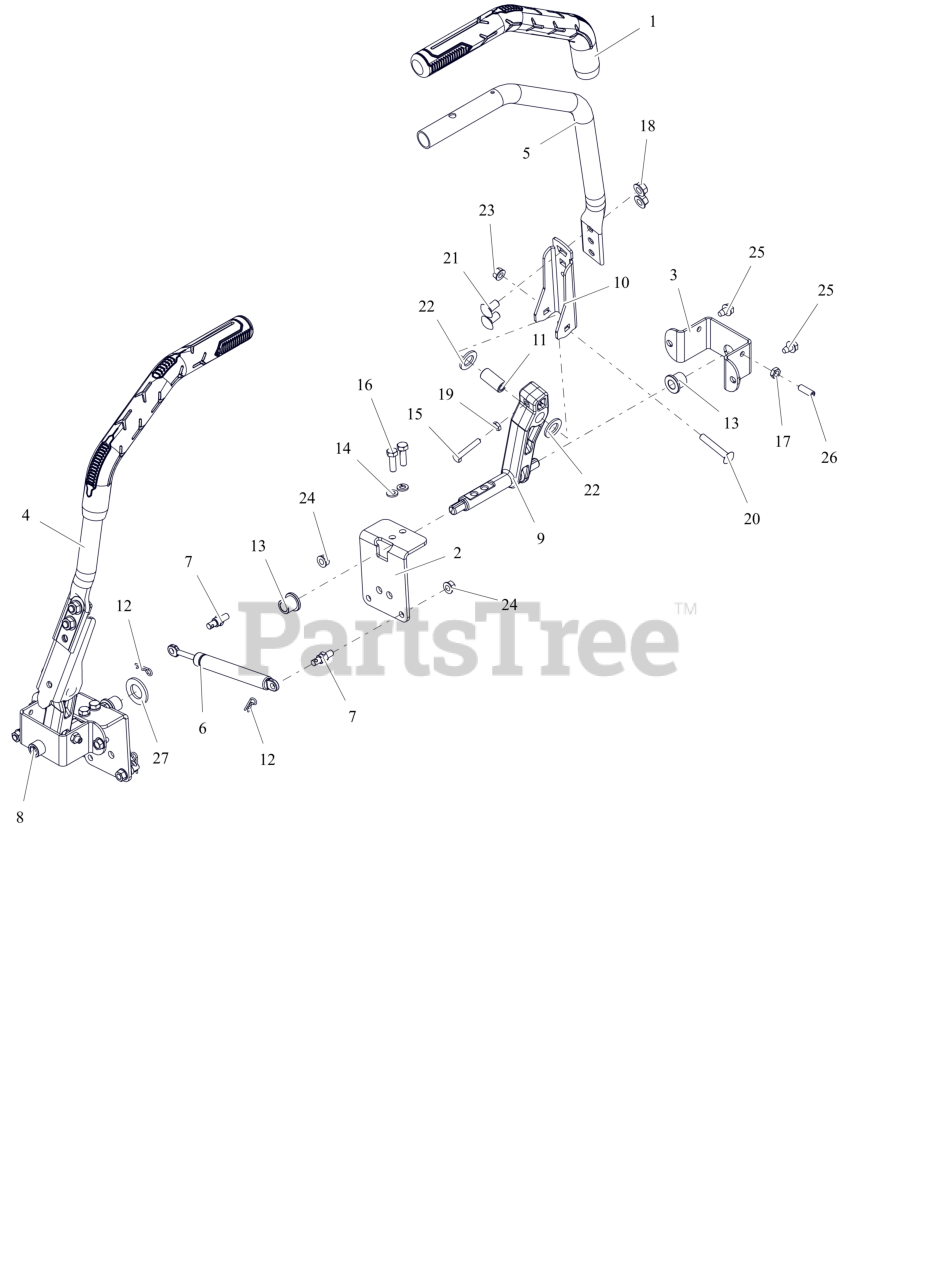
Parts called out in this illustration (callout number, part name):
1	GRIP, ARIENS HANDLEBAR
2	BRKT, STEEERING
3	BRKT, STEERING
4	HANDLE, STEERING-RH
5	HANDLE, STEERING-LH
6	DAMPER, STRAIGHT MOUNT
7	COUPLER, DAMPER MOUNT
8	ARM- STEERING-RH LOWER (MACH)
9	ARM- STEERING-LH LOWER (MACH)
10	ARM, CONTROL UPPER
11	BSHG-SLV .342 X .627 X 1.331
12	PIN, HAIR #213 .08X1.19 ZCC
13	BHSG-FLG .500X.750X.750X.125
14	WSHR,LK-REG .312X.078 ZCC
15	BLT, HEX .25-20X1.50F G5 ZCC
16	BLT, HEX .31-18X1.00 G8 ZCC
17	NUT-JAM .312-18 G2 ZCC
18	NUT-LK-TOP-FLG .375-16 GG ZCC
19	NUT-JAM .250-20 G2 ZCC
20	BLT, RHSSN .31-18X2.00 G5 ZCC
21	BTL,RHSSN .375-16 X 0.75 G5 FPB
22	WSHR, FRICTION
23	NUT,LK-CTR-FLG .31-18 GF ZCC
24	NUT-LK-TOP-FLG .312-18 GF ZCC
25	SCR,TAP .312-18X.50 HWH TR ZCC
26	SCR-SET, .312-18X1.000
27	WSHR, FLT .812X1.469X.134 ZCC
